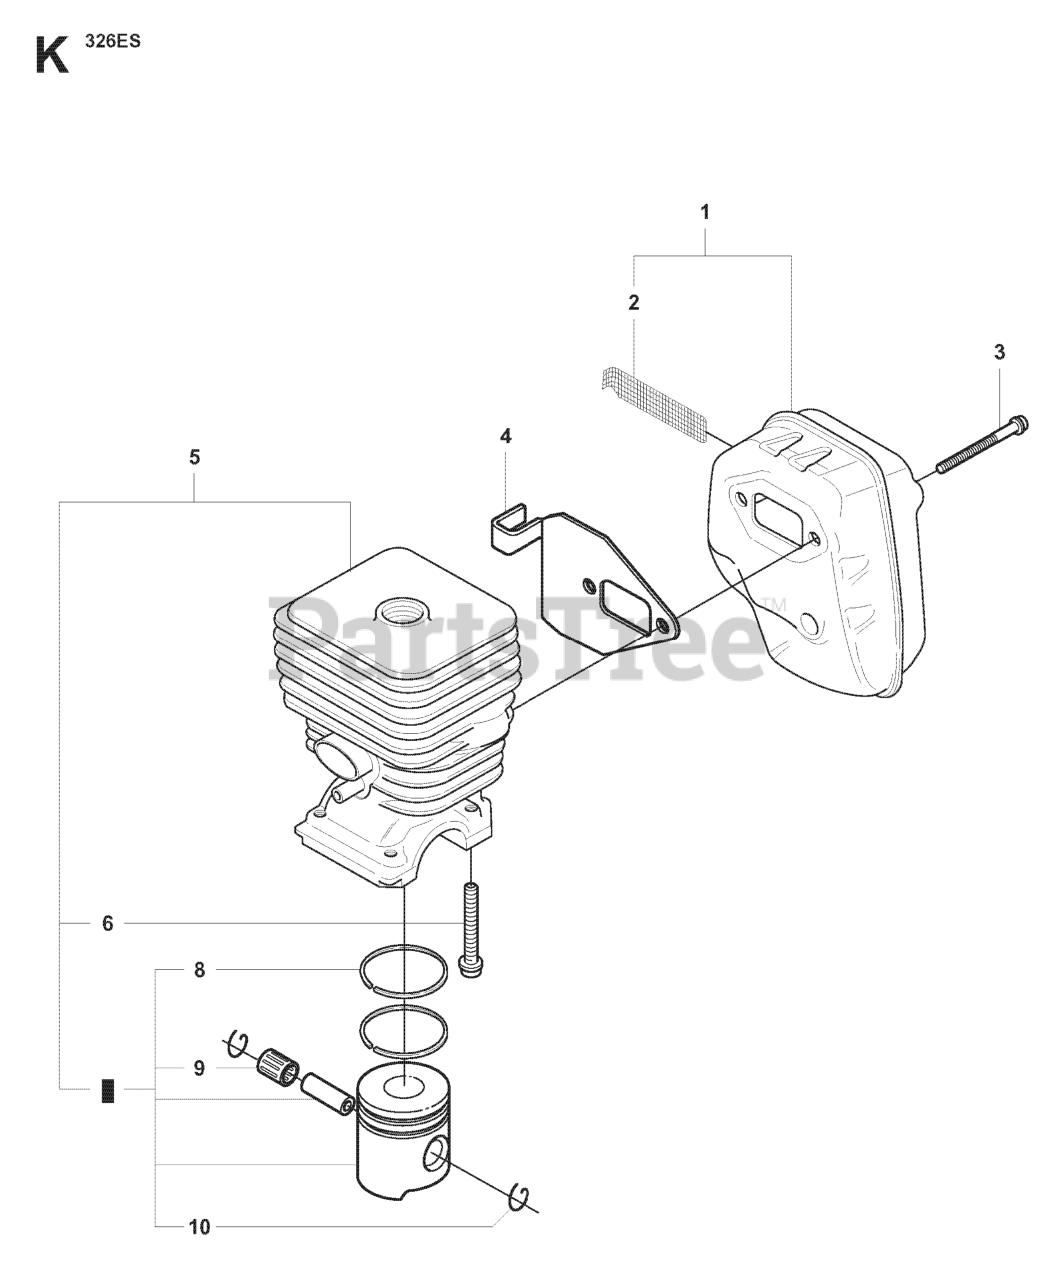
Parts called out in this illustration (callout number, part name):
2	SPARK ARRESTOR SCREEN
5	CYLINDER
6	SCREW
8	PISTON RING
